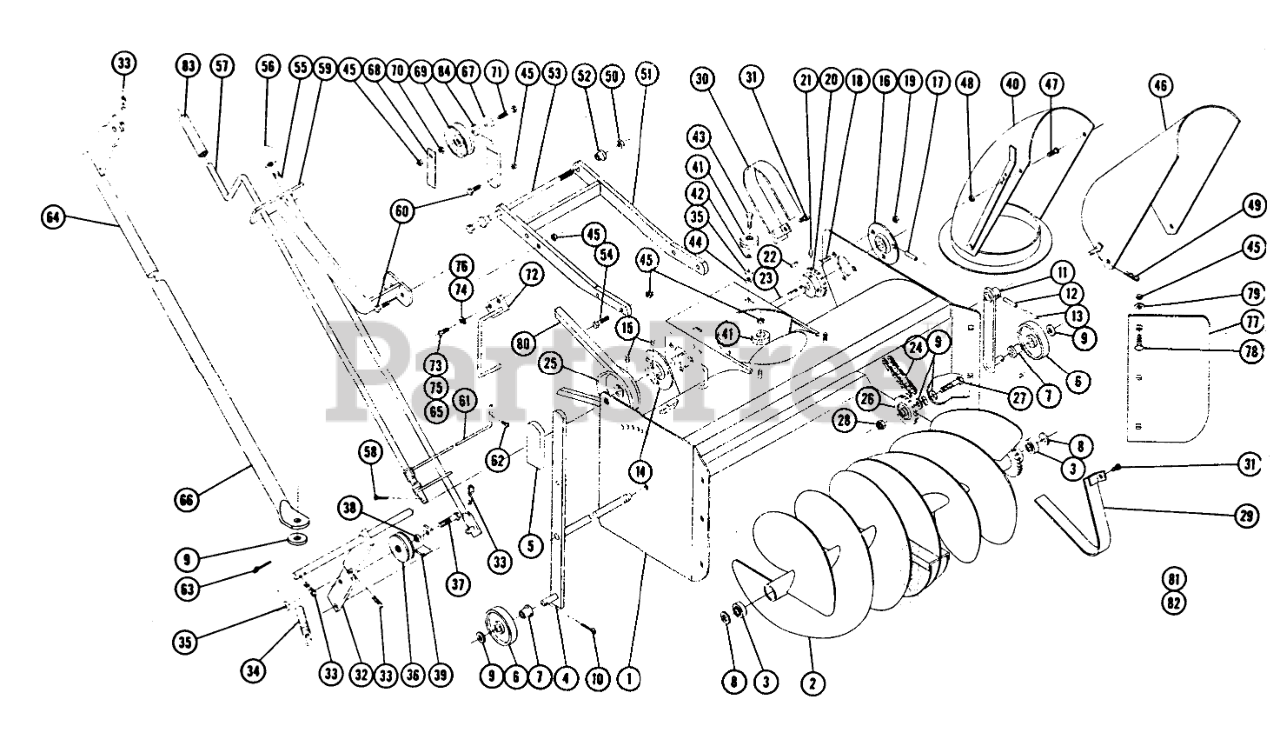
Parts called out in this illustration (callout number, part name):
1	Ass-y Wrapper
2	Auger
3	Bearing
4	Auger Shaft
5	GRIP
6	Wheel
7	Bushing
8	Washer Auger
9	Washer
10	Cotter Pin
11	Wheel Support
12	ROLL PIN 1/4 X 1-1/4
13	Roll Pin 5/32 x 1/4
14	Bearing-Flanged
15	Set Screw 5/16-18 x 5/16
16	Bearing Flanged
17	PIN-ROLL, SPIROL
18	Bolt Hex 5/16-18 x 3/4
19	Nut-Nylok
20	SPROCKET
21	Set Screw 1/4-20 x 1/4
22	Key
23	Shaft Drive
24	Chain
25	Pulley Drive Shaft
26	Idler Sprocket
27	Bolt-1/2-13-1 3/4
28	Nut-ES 1/2-13
29	Ass-y Guard-Inner
30	Guard-Outer
31	SCREW
32	Ass-y Idler Bracket
33	Hairpin
34	Spring
35	Washer
36	Pulley
37	Bolt 3/8-16 x 1 1/4 Nylok
38	BUSHING
39	Clip - Belt
40	S/A SHROUD R
41	Roller
42	SPACER
43	Bolt 1/4 20 x 1 1/4
44	Nut-Nylok
45	3/8-16 E.S.
46	Deflector
47	Bolt Rd. Hd. 1/4-20 x 1/2
48	Nut, 1/4-20
49	Hairpin
51	Ass-y Mounting Frame
52	Spacer
53	Bolt-Hex. 3/8-16 x 8 1/2
54	Bolt 3/8-16 x 7/8
55	Ass-y Rod-Clutch
56	Knob
57	Crank
58	Cotter Pin
59	Control Guide Bracket
60	Bolt 3/8-16 x 1
61	Cable
62	Screw-Rd. Hd. Mach. #6-32 x 1/4
63	Cotter Pin 3/16 x 1
64	Lid Rod
65	Screw Round Hd. 5/6-18 x 3/4 (Kohler 10 H.P.)
66	Lift Tube
67	Bracket-Idler
68	Bar Belt Guide
69	Pully-Idler
70	3/8-16 Jam Nut
71	Bolt 3/8-16 x 2 1/4
72	Ass-y. Belt Stop
73	Bolt Round Head 5/16-24 x 3/4
74	Lockwasher
75	Screw 1/8-16 x 3/4
76	Lockwasher
77	Plate-Side Extension
78	Bolt 3/8-16 x 1
79	Washer
80	V-BELT
81	Decal-Caution
82	Decal
83	Tube
84	SPACER
